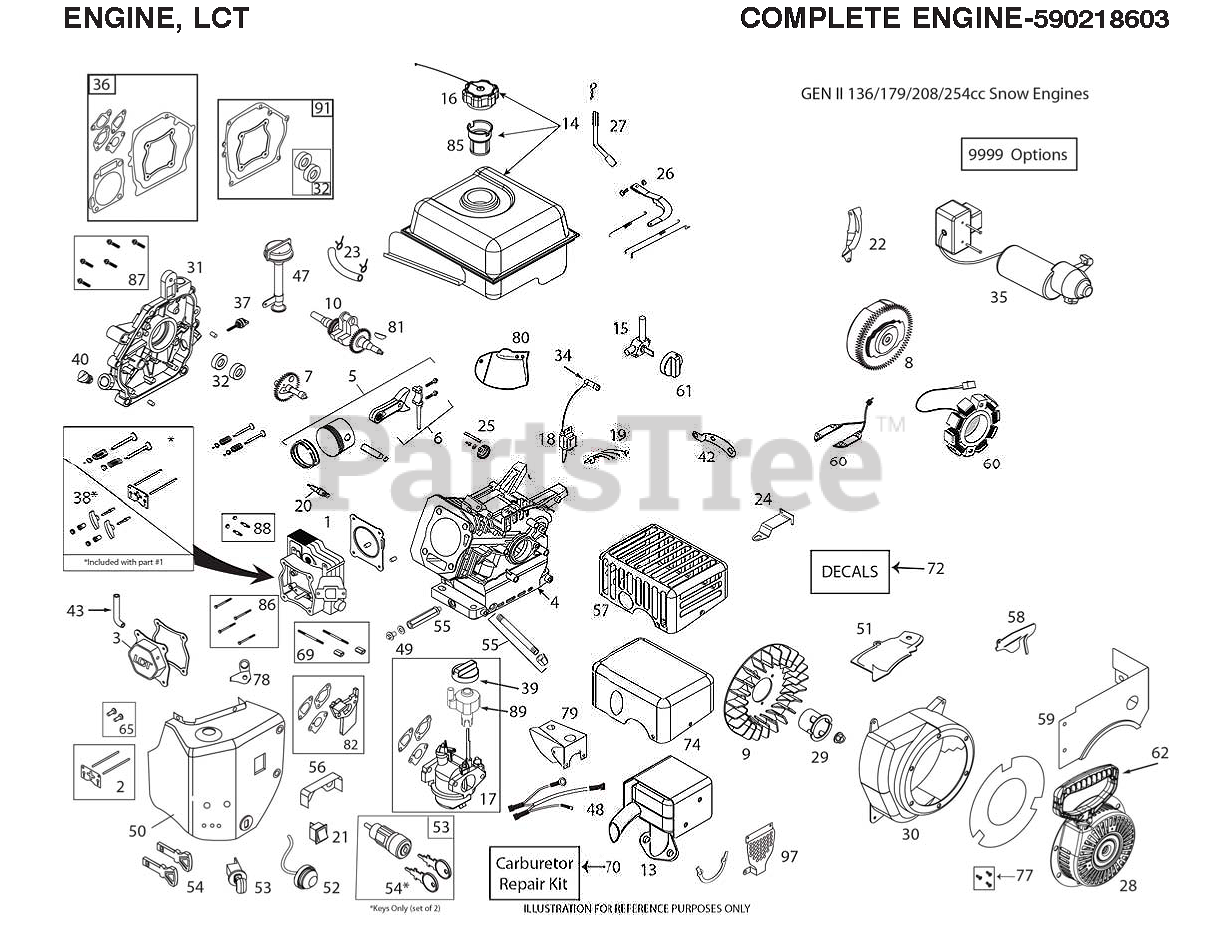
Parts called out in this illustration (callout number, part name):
1	CYLINDR.HEAD.SRV.KIT W/GASKET
2	KIT.PUSH.ROD.SRV(SK208-1001)
3	VALVE COVER ASSEMBLY
5	KIT.PISTON.SRV(SK208-1400)
7	KIT.CAMSHAFT.208CC.LCT
8	FLYWHEEL ELECTRIC START W/6 MA
9	FLYWHEEL FAN 420586
10	CRNKSHFT-KYD#14.208CCSKSNO8001
13	MUFFLER KIT LCT SKSN2205.1
14	FUEL.TK.ASSY.GENII.SKSN0311.1
15	FUEL.PETCOCK.SNOW(SKSN4900)
16	FUEL CAP OVERSIZED CLICK STYLE
17	CARBURETTOR L10-1D.W/SP
18	208CC IGN COIL (STD)
20	SPARK.PLUG(2083810)
21	SWITCH.ON/OFF(SKSN-0403)
22	SHIELD.FLYWHEEL.ELEC.STRT.208C
23	FUEL HOSE KIT
24	SPEED.CTRL.BRKT.(SKSN0150)
25	GOVENOR.GEARS ASM(SK2082900)
26	CARBURETTOR GOVERNOR LINK.ASM.
27	KIT.GOVERNOR.CRANK(SK208-3100)
28	RECOIL.STRT.ROUND(BLK) SNOW
29	STRTER.CUP(NON-SLOT)SKSN0601.2
30	BLOWER HOUSING ASSY
31	COVER CRANKCASE.LCT.SK2083605
32	SEAL KIT (2 PCS)
34	SPARK.PLUG.BOOT.SNW,SKSN4691.1
35	ELEC.START.GEN2.SKSN0451.1
36	GASKET.KIT.208CC(SK2084300.1)
37	DIPSTICK SMALL
38	ROCKER ARM KIT
39	CHOKE.KNOW.SNOW(SKSN4500)
40	NON REMOVABLE PLUG
43	TUBE.BREATHER.LCT.208
47	TUBE ASSY HIGH OIL-FILL
48	HARNESS WIRE. W/O OFF/ON SWITC
49	KIT.OIL.DRAIN.PLUG(SK2089911
50	BOX HEATER.W/O OFF/ON SWITCH.L
51	SHIELD.CYLINGER.LCT.SKSN0608.1
52	PRIMER.BULB.WITH HOSE (SNOW)
53	SWITH.KEY.ASSEM.SNOW.SINGLE.ST
54	KEY SET(2 KEYS) SKSN0407.1
55	EXTENDED OIL DRAIN TUBE
58	SHIELD GOVENOR & CARB - COMPOS
59	FUEL.TNK.SKRT.GENII.SKSN0103.1
60	208CC 60W ALTERNATOR
61	FUEL KNOB-SNOW
65	TAPPET.KIT.LCT.208CC
69	CARB.STUDS & COUPLING KIT.SNOW
70	CARBURETOR.REPAIR KIT.LCT.
74	MUFFLER GUARD.EUR./LCT.SKSN220
77	BOLT.KIT.RECOIL.LCT.ALL.ENGINE
81	KEYS.FLYWHEEL.208/414CC.5PACK
82	SPACER.CARBURETOR.208CC.LCT
85	STRAINER.FUEL.TANK.LCT.208CC
86	BOLT KIT.CYLINDER HEAD.LCT(4)1
87	KIT.BOLT.CRANKCASE.COVER.6PC
88	STUD.MUFFLER.KIT.LCT
89	COVER CRANKCASE GASKET
91	CRANKSHAFT GASKET KIT.LCT
97	MUFFLE MANIFOLD GUARD.LCT
9999	HIGH.ALTITUDE.JET 6,000FT
9999	KIT.BOLT.LCT.SK9990.1
9999	STARTER SCREW.STARTER SWITCH B
